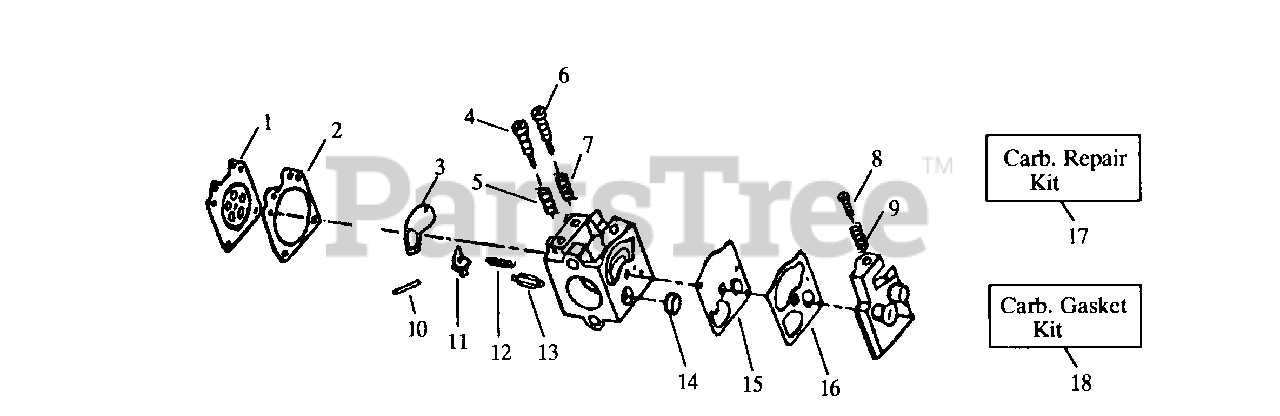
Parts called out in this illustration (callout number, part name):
1	Metering Diaphragm
2	Metering Diaphragm Gasket
3	Circuit Plate Gasket
4	Hi Speed Needle
5	Hi Speed Needle Spring
6	Idle Needle
7	Idle Needle Spring
8	Idle Speed Screw
9	Idle Speed Spring
10	Metering Lever Pin
11	Metering Lever
12	Metering Lever Spring
13	Inlet Needle Valve
14	Inlet Screen
15	Pump Diaphragm
16	Pump Gasket
17	Carb. Kwik Repair Kit
18	Carb. Gasket/Diaphragm Kit
